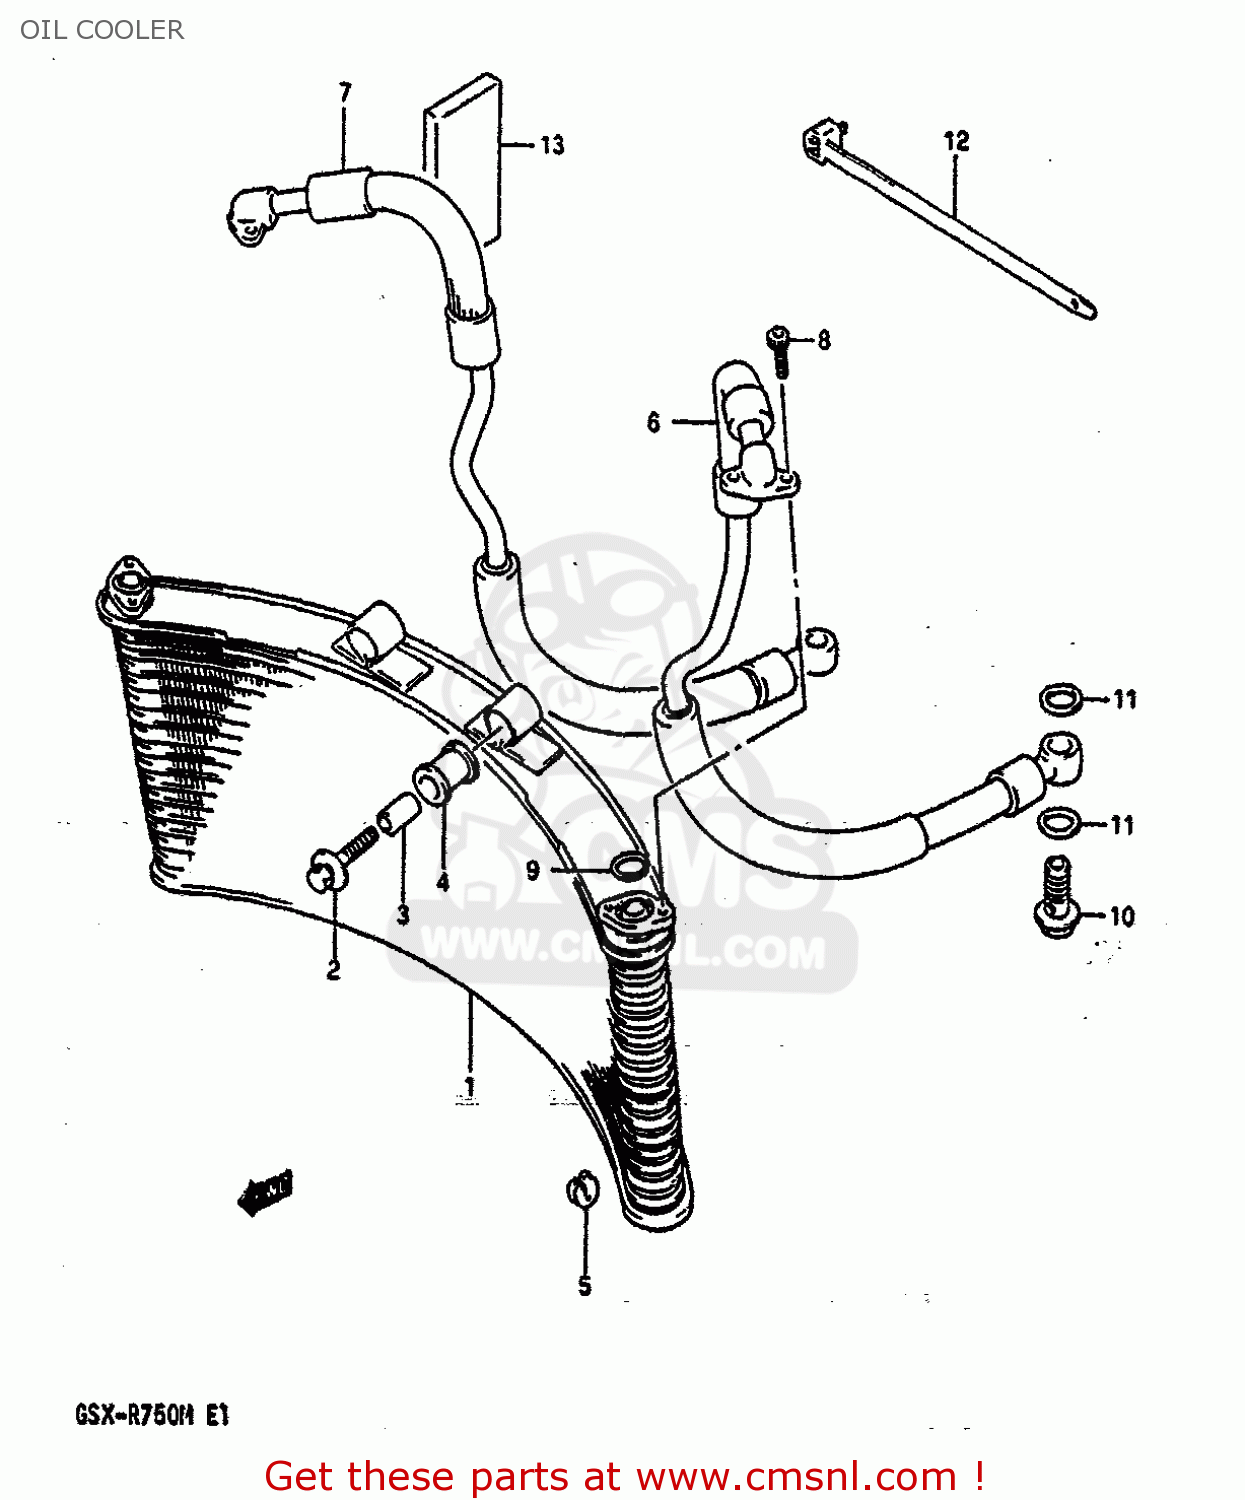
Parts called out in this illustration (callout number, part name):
1	COOLER ASSEMBLY,OIL
2	BOLT(8X40)
3	SPACER (8.8X12X24.5)
4	CUSHION,OIL COOLER NO.1
5	CUSHION,OIL COOLER NO.2
6	HOSE,COOLER,L
7	HOSE,OIL COOLER,R
8	BOLT
9	O RING(D:2.4,ID:12.3)
10	BOLT UNION
11	GASKET(16X22X2) (NAS)
12	CLAMP
13	PROTECTOR
